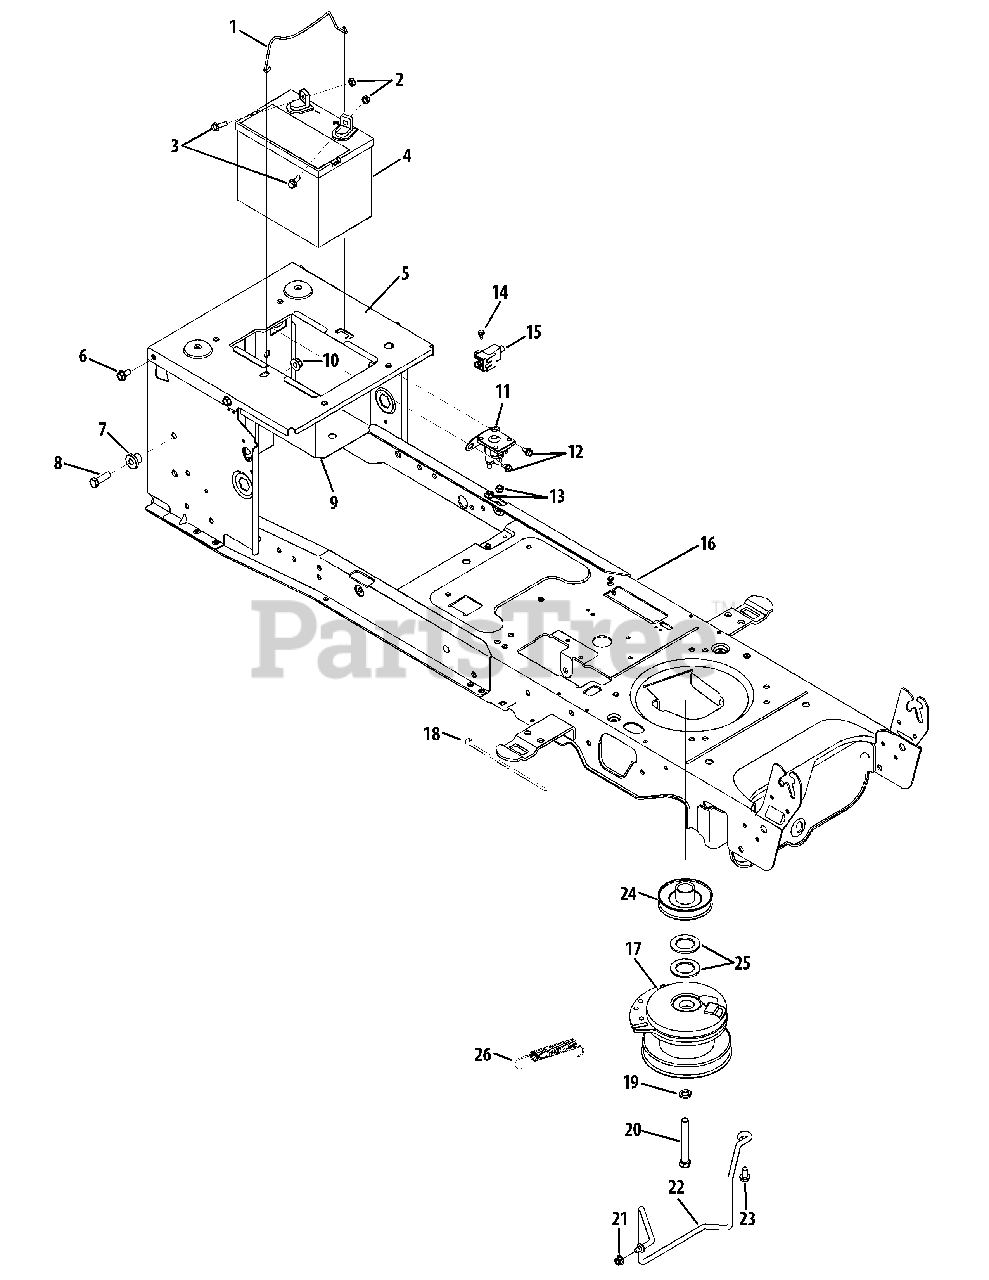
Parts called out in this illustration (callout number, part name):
1	Battery Hold Down Rod
2	Sems Hex Nut 1/4-20
3	Hex Hd. Flg. Screw. 1/4-20 x .75 Gr. 5
4	Battery
5	Seat Frame Bracket
6	Hex Wash Hd. Tapp Screw. 5/16-18 x .75
7	Shoulder Spacer .38 x 1.0 x .70
8	Hex Bolt 3/8-16 x 1.25
9	Battery Tray
10	Flange Lock-Nut 3/8-16 Gr. F Nylon
11	Solenoid
12	Hex Wash HD Tapp Screw 1/4-20 x .375
13	Hex L-Flanged Nut 1/4-20 Gr. F Nylon
14	Shoulder Screw #10-32 x .50
15	Switch, Interlock
16	Lower Frame Assembly
17	Electric PTO Clutch (42" deck)
17	Electric PTO Clutch (46" deck)
17	Electric PTO Clutch (50" deck)
18	Cable Tie
19	Lockwasher 7/16 ID
20	Hex Cap Lock Screw 7/16-20 x 3.5 Gr. 5
21	Flange Locknut 5/16-18 Gr. F, Nylon
22	Keeper Rod (42" & 46")
22	Keeper Rod (50" & 54")
23	Hex Wash Hd. Tapp Screw. 5/16-18 x .75
24	Engine Pulley
25	Flat Washer 1.03 ID x 1.64 OD x .095
26	Ext. Spring .5 OD x 5.52" Lg. (54")
